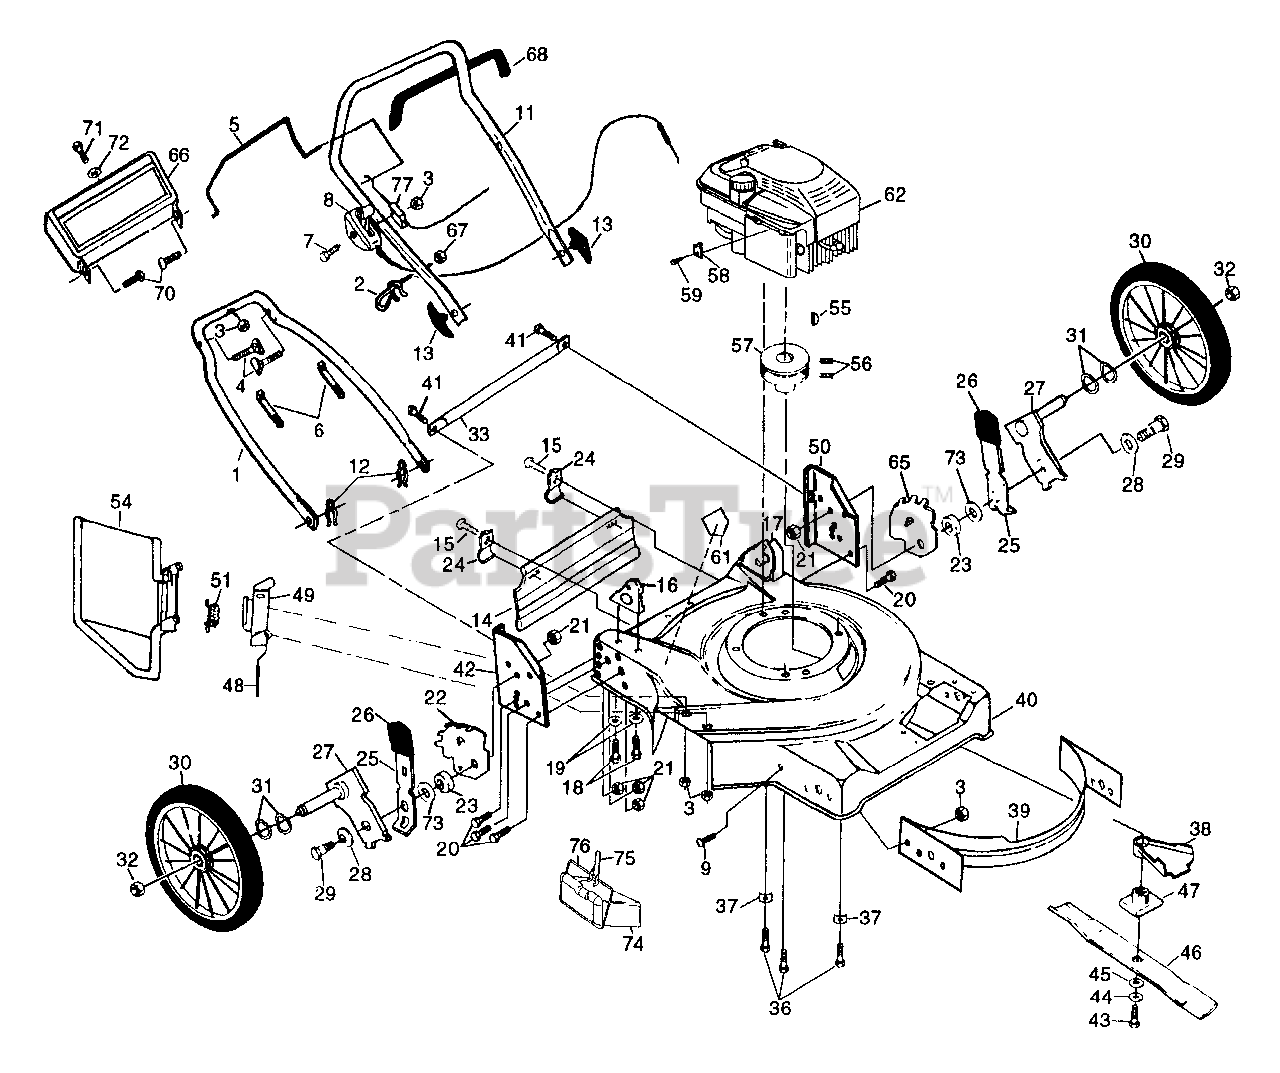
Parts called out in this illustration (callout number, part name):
1	Lower Handle
2	Rope Guide
3	Locknut 1/4-20
4	Handle Bolt
5	Control Bar
6	Wire Tie
7	Hex Head Screw 1/4-20 x 2.12
8	Throttle Control
9	Screw 1/4-20 x 3/4
11	Upper Handle
12	Hairpin Cotter
13	Handle Knob
14	Rear Skirt
15	Hex Head Screw
16	Handle Bracket Assembly (Right)
17	Handle Bracket Assembly (Left)
18	Screw 5/16-18 x 3/4
20	Bolt, Hex Head 3/8-16 x 3/4
21	Locknut
22	Wheel Adjusting Bracket (R.R.)
23	Spacer
24	Skirt Bracket
25	Selector Spring
26	Selector Knob
27	Axle Arm Assembly
28	Rear Spring Washer
29	Shoulder Bolt 3/8-16
30	Wheel & Tire Assembly (Rear) 14 x 2
31	Wave Washer
32	Nut
33	Rod Support
36	Thread Rolling Screw 3/8-16 x 1
37	Engine Washer
38	Debris Shield
39	Front Baffle
40	Mower Housing Kit
42	Wheel Support Bracket R.H.
43	Hex Head crew 3/8-24 x 1-3/8 Gr. 8
44	Helical Washer 3/8
45	Hardened Washer
47	Blade Adapter
49	Housing Bracket
50	Wheel Support Bracket L.H.
51	Torsion Spring
54	Discharge Guard
55	Hi-Pro Key
57	Engine Pulley
58	Cable Clamp
59	Screw #10 x 5/8
61	Danger Decal
65	Wheel Adjusting Bracket (L.R.)
66	Trim Plate Handle Asm.
67	Keps Locknut 1/4-20
68	Handle Grip
70	Self Tapping Screw 10-24 x .625
71	Hex Hd. Wash. Screw 1/4-20 x 1-1/2
72	Flat Washer 28 x .62 x .06
73	Flat Washer 3/8
74	Mulcher Plug
75	Plug Latch
76	Mulcher Bail
77	Zone Control Cable
